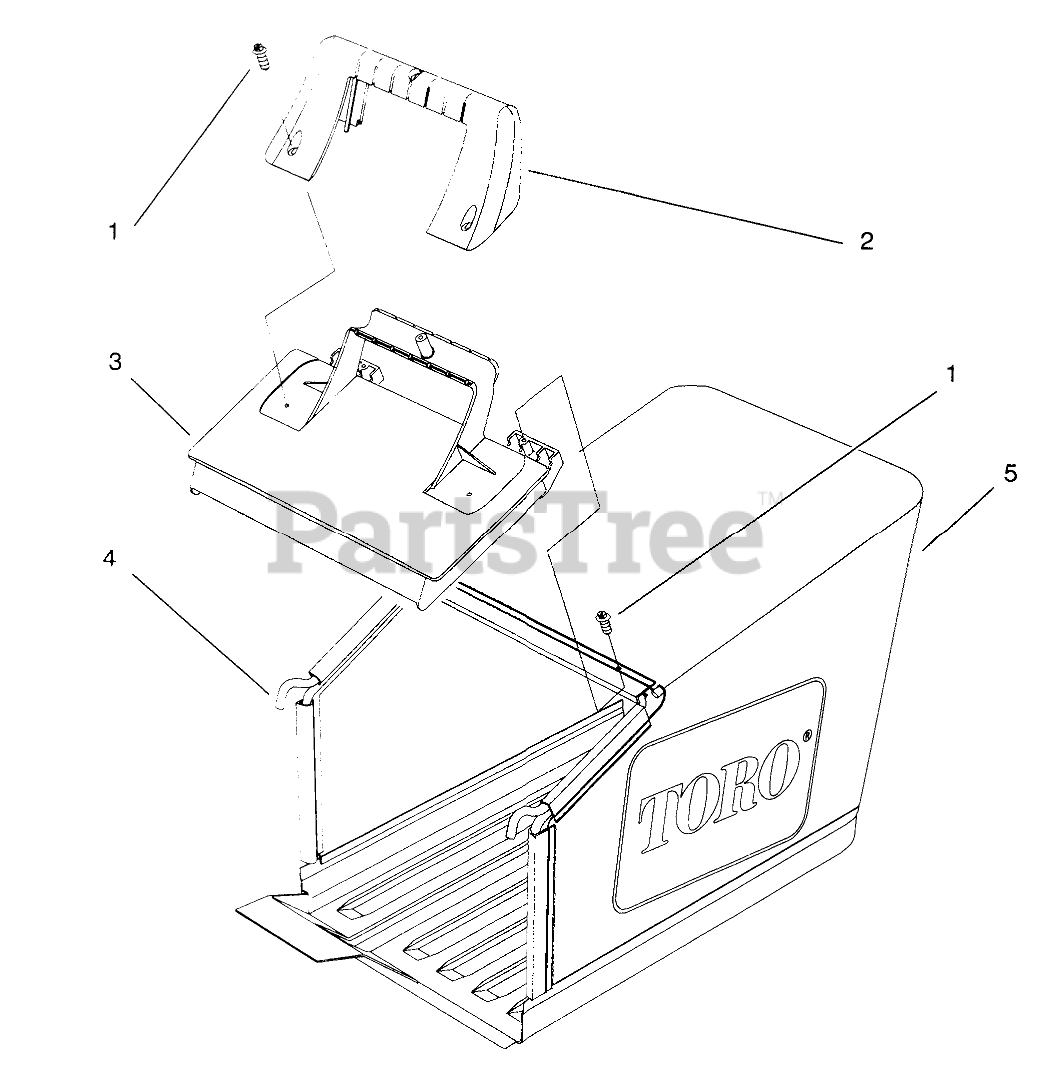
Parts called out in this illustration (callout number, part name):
1	SCREW-PPH
2	HANDLE-DOOR
3	DOOR-BAG
4	Frame
5	GRASS BAG 48CM W/PAN
